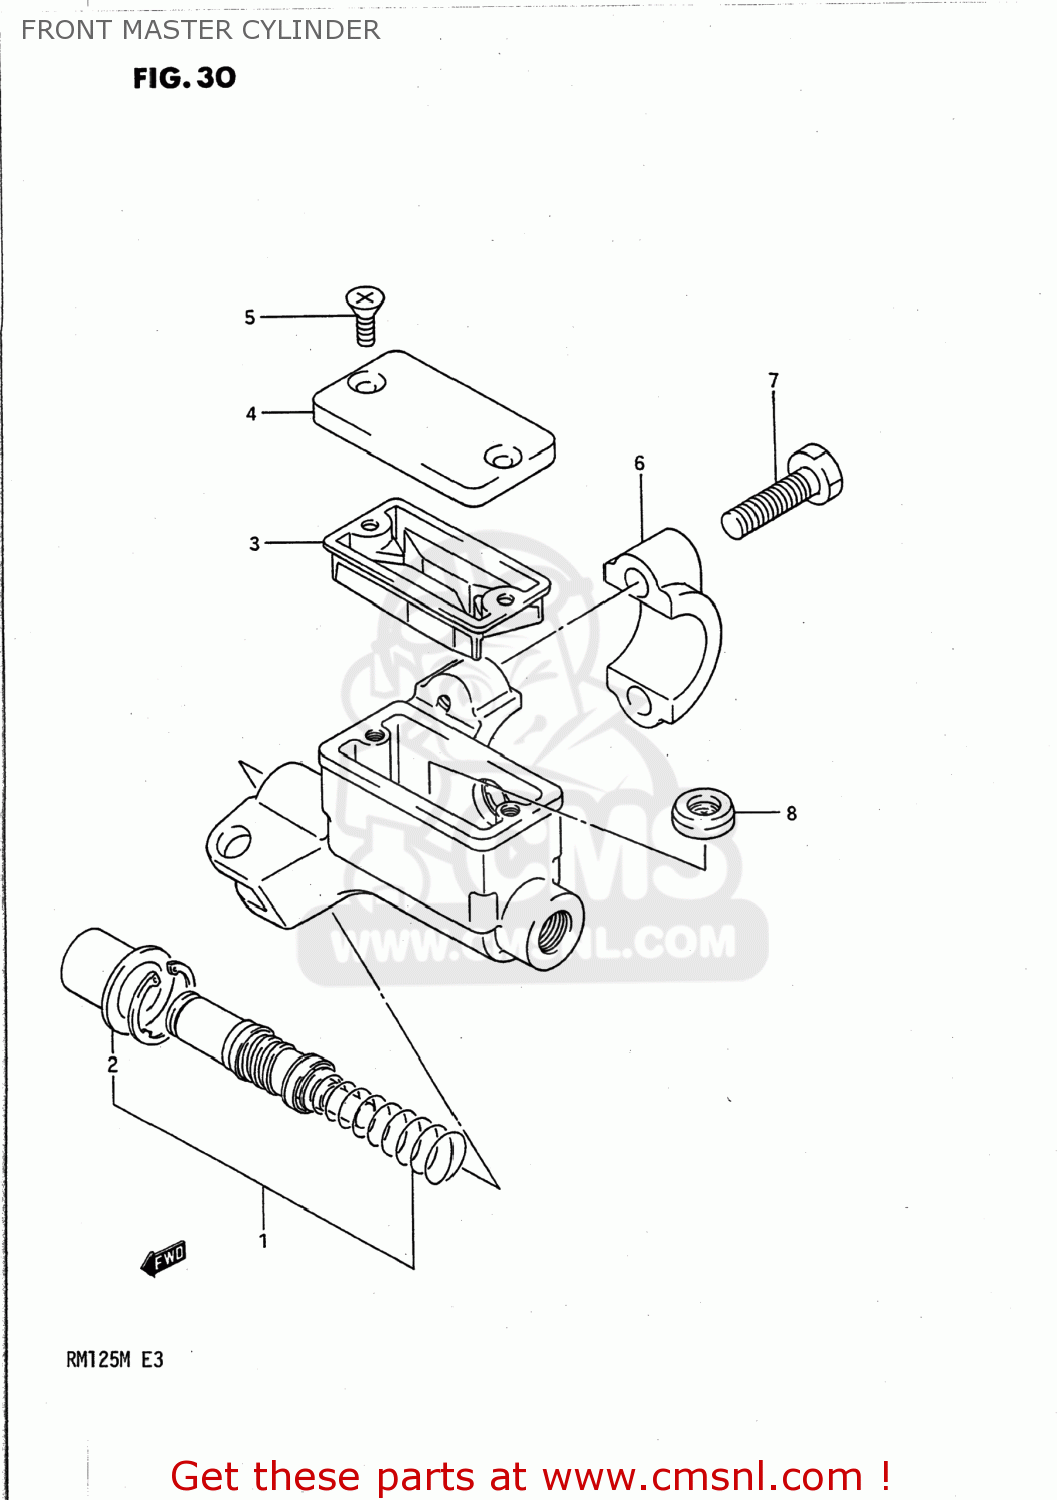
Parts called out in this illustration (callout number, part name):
1	PISTON & CUP SET
2	BOOT
3	DIAPHRAGM
4	CAP
5	SCREW
6	HOLDER
7	BOLT
8	SEPARATOR
